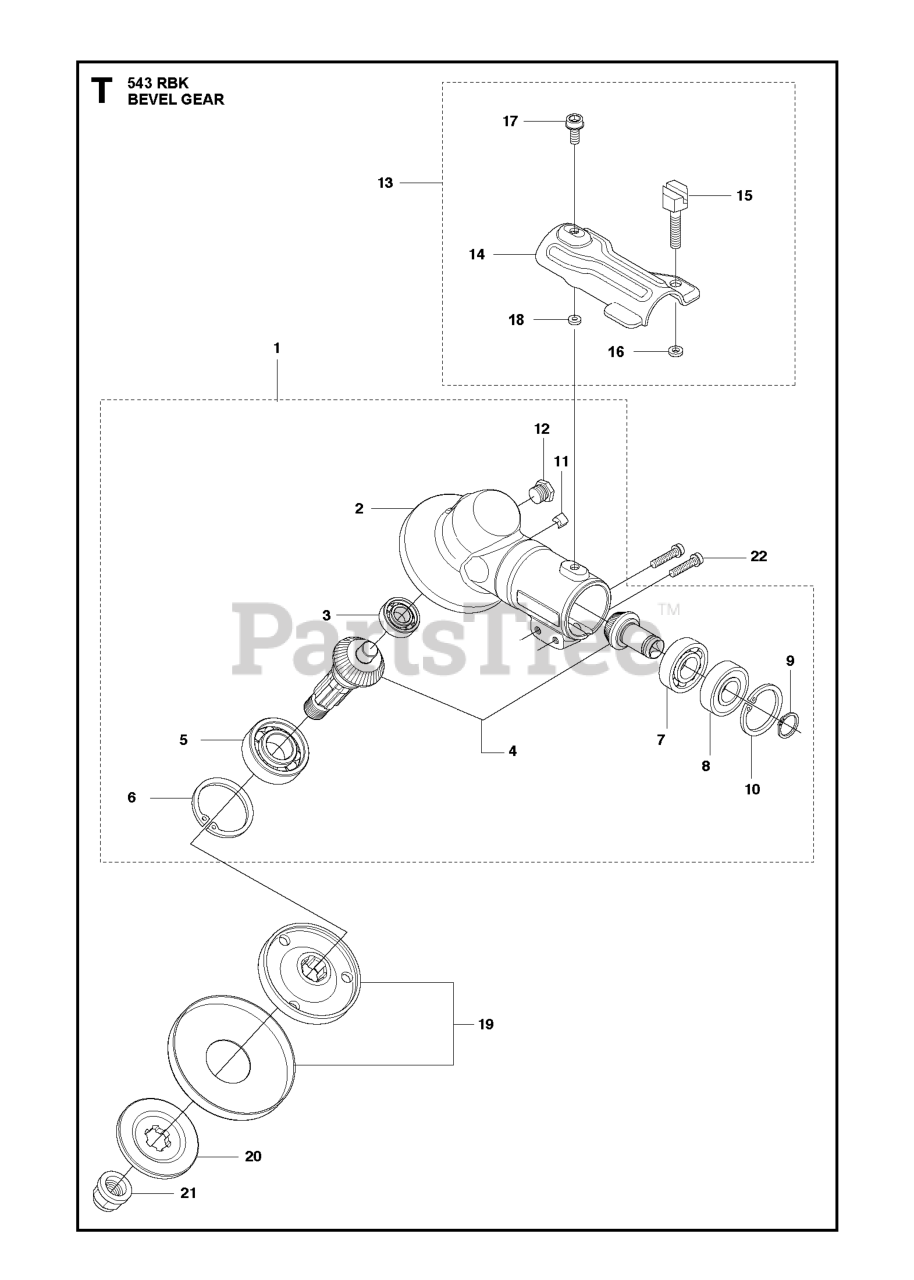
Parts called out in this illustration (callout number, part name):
1	GEAR CASE SET
3	BALL BEARING 24X9X1/609ZR
4	SPARE PARTS KIT
5	BALL BEARING
6	RETAINING RING
7	BALL BEARING
8	BALL BEARING
9	SEEGER CLIP
10	RETAINING RING SGH 28
13	CLAMP
14	RP HOLDER
16	LOCKING NUT M6
17	SCREW
18	LOCKING NUT
20	RP FLANGE
21	BLADE NUT
